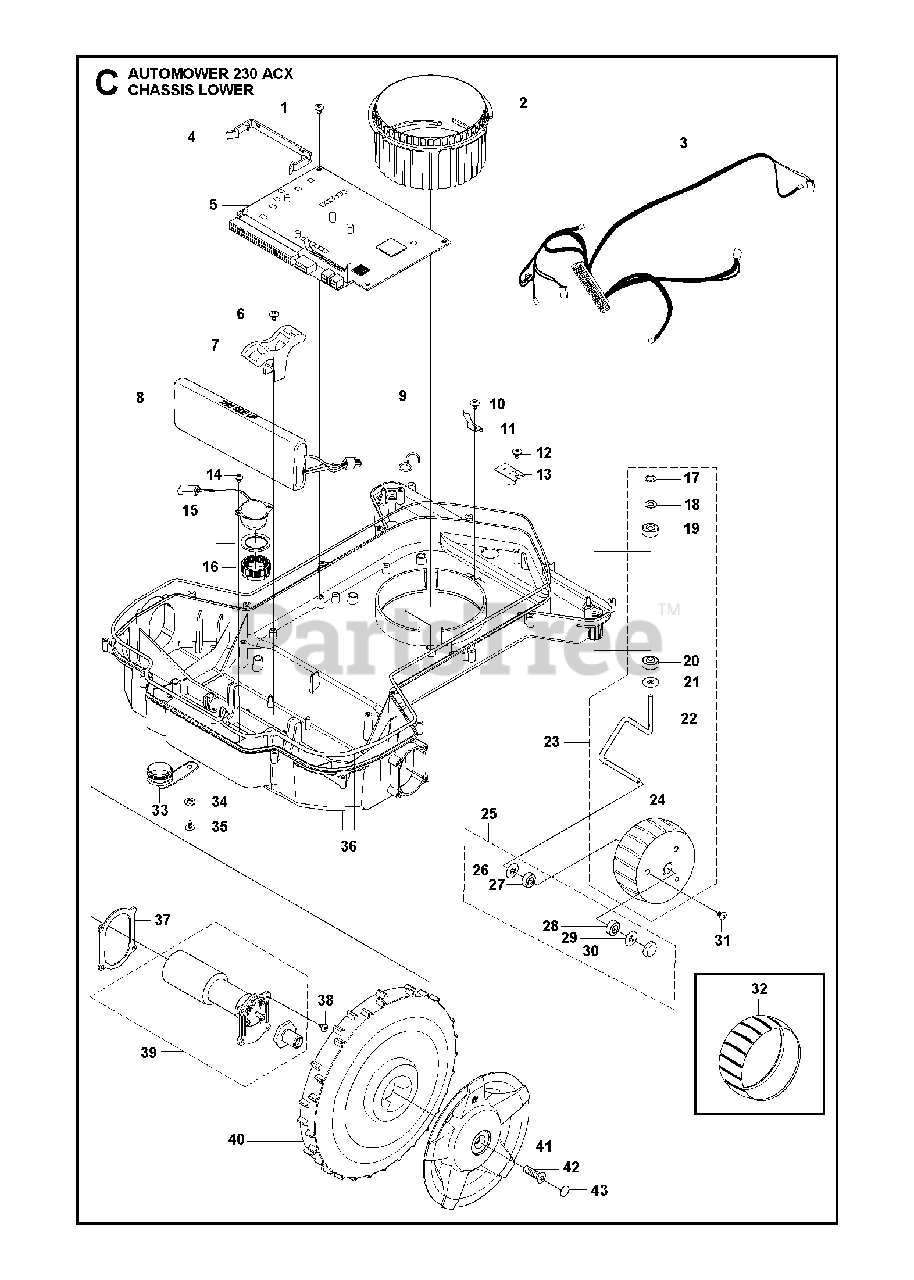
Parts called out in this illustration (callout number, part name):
1	SCREW SILVER 10MM
2	CUTTING HEIGHT NUT
3	MAIN WIRING
4	CLIP MAIN CONNECTOR
4	CLIP MAIN CONNECTOR 50PCS
6	SCREW 14MM
8	BATTERY
12	SCREW SILVER 10MM
13	PRINTED CIRCUIT ASSY
16	NUT BUZZER
17	LOCK WASHER
18	WASHER 6.4X12X1.6 SS
19	BALL BEARING
20	BALL BEARING
21	WASHER
22	SPINDLE
23	KIT 6MM AXLE KIT - STANDARD WH
24	WHEEL, FRONT
25	BEARING KIT 6MM AXLE
26	WASHER
27	BALL BEARING
28	BALL BEARING
29	WASHER
30	COVER WASHER
31	SCREW ITXPANT PT 40 THREAD
32	WHEEL RUBBER TYRE
33	PLUG SERVICE PLUG
35	SCREW 14MM
36	CHASSIS LOWER
39	DRIVE MOTOR
40	REAR WHEEL
43	COVER WASHER
